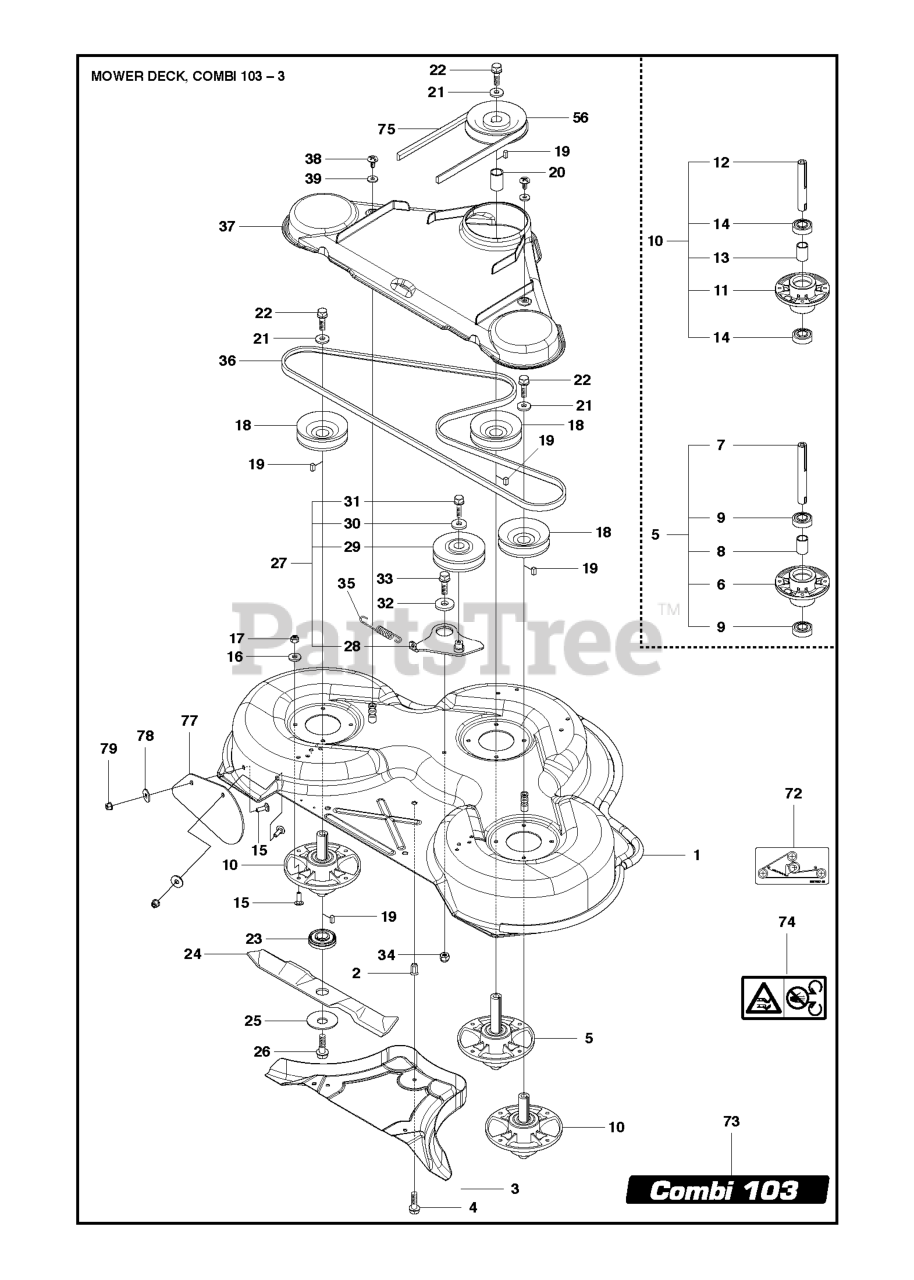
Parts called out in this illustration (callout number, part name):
6	BEARING HOUSING
9	BALL BEARING
11	BEARING HOUSING
14	BALL BEARING
16	WASHER BRB 8.4X17
17	LOCKNUT M8
34	LOCKNUT M8
79	NUT FLANGE
